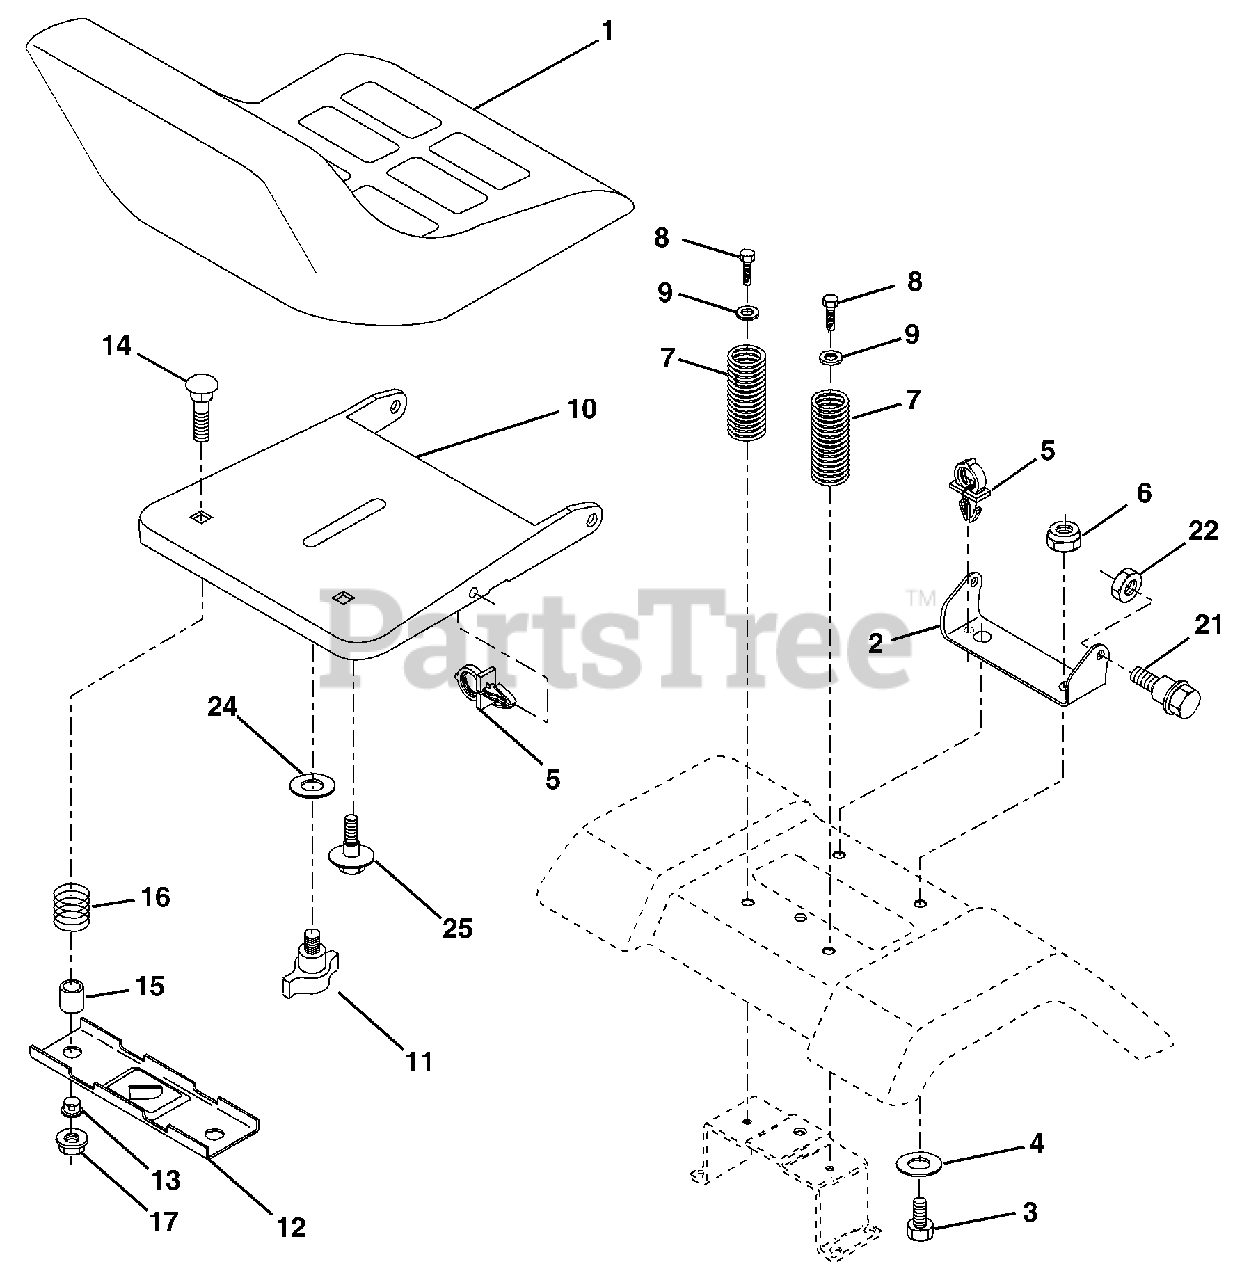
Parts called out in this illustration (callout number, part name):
1	Seat
2	Bracket Pivot Seat 8 720
3	Bolt Fin Hex 3/8-16 unc x 1
4	Washer Flat 13/32 x 1 x 10 Ga.
5	Clip Push-In
6	Nut Hex w/Ins. 3/8-16 unc
7	Spring Seat Cprsn 2 250 Blk Zi
8	Screw 3/8-16 x 1
9	Washer 13/32 x 1 x 14 Ga.
10	Pan Seat
11	Knob Seat Adj. Wingnut
12	Bracket Mounting Switch
13	Bushing Snap Blk Nyl 50 Id
14	Bolt Rdhd Sqnk 1/4-20 x 1-1/2
15	Spacer Split
16	Spring Cprsn
17	Nut Lock 1/4 Lge Flg Gr. 5 Zinc
21	Bolt Shoulder 5/16-18 unc
22	Nut Hex Lock W/Ins 5/16-18
24	Washer 17/32 x 1-3/16 x 12 Ga.
25	Bolt Shoulder 5/16-18 x 62
